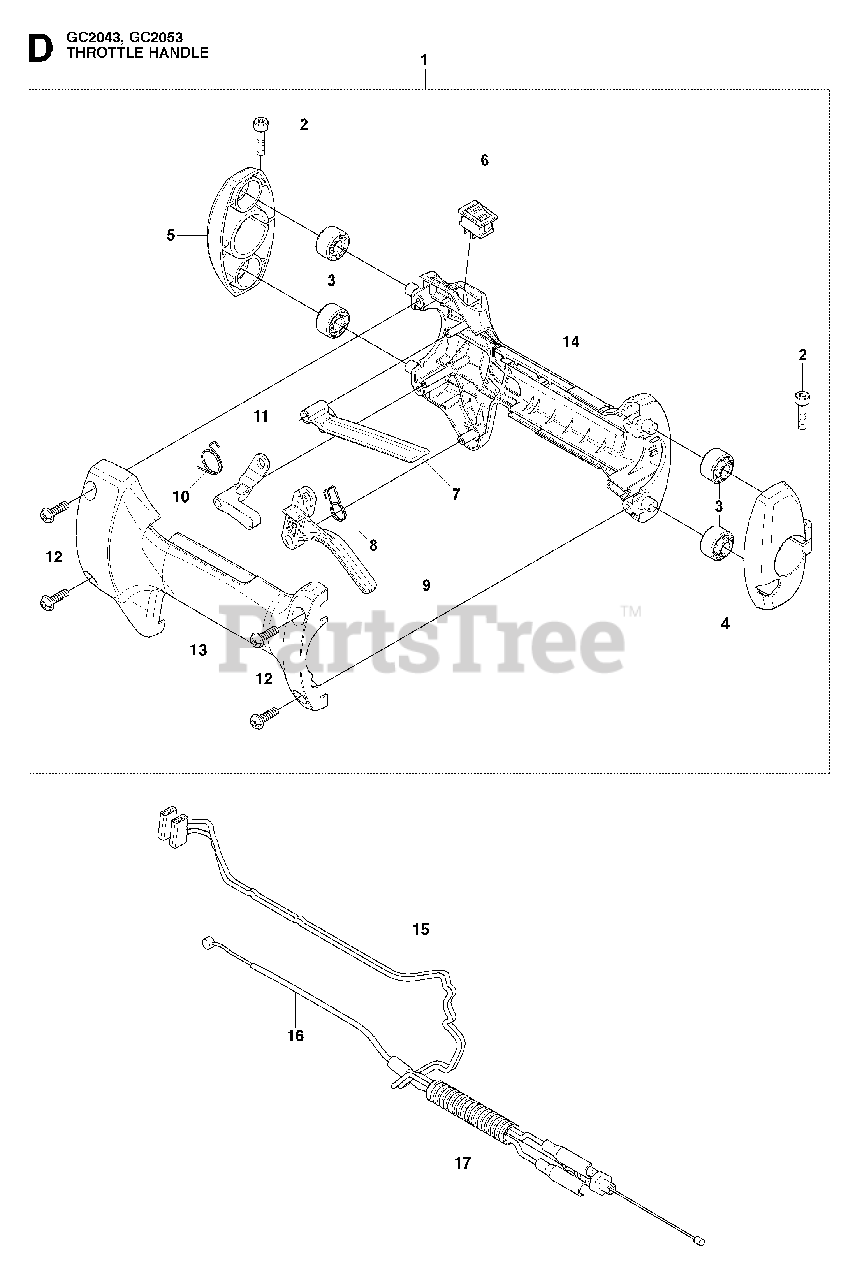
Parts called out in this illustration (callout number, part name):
2	BOLT TORX M5XL20 T27
6	SWITCH
10	SPRING
